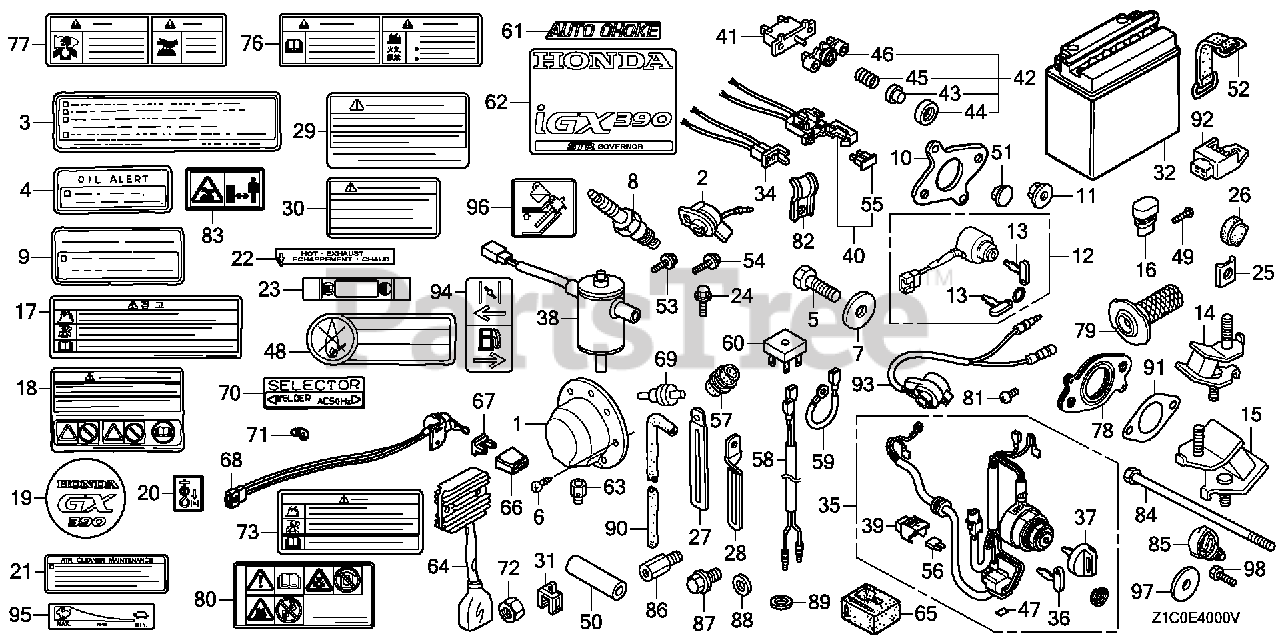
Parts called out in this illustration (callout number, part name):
18	MARK, OPERATOR CAUTION (Honda Code 8018962). (FRENCH)(MADE IN THAILAND)
29	MARK, OPERATOR CAUTION (FRENCH)(MADE IN THAI)
30	MARK, EX. CAUTION (FRENCH)
